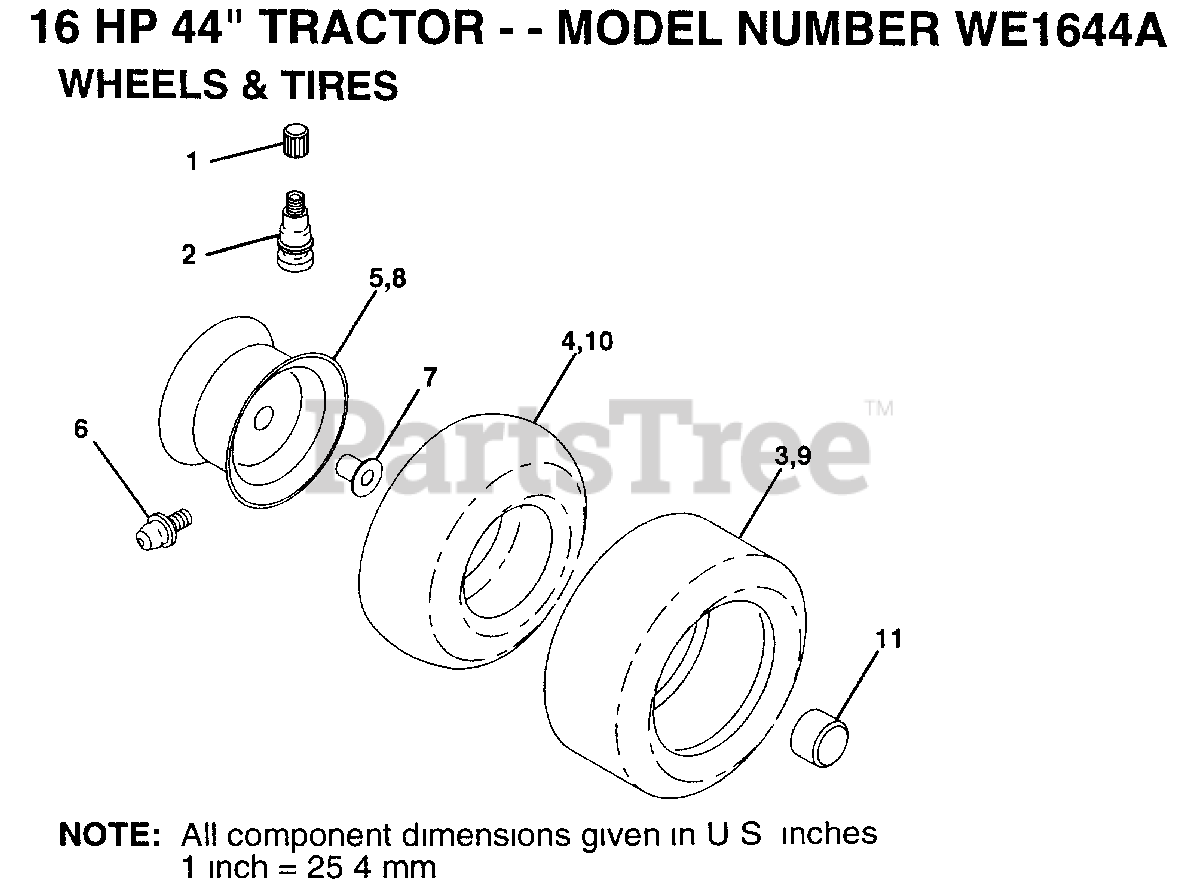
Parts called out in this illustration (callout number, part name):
1	VALVE CAP
2	VALVE STEM LT
4	TUBE.5.3/4.5/6
5	"RIM.FRONT.8"".YEL"
6	FITTING LT
7	"FLANGE, BEARING"
8	"RIM.REAR.12"".YEL"
9	TIRE.R.23X9.5-12
10	TUBE.23X8/10-12
11	HUB CAP
